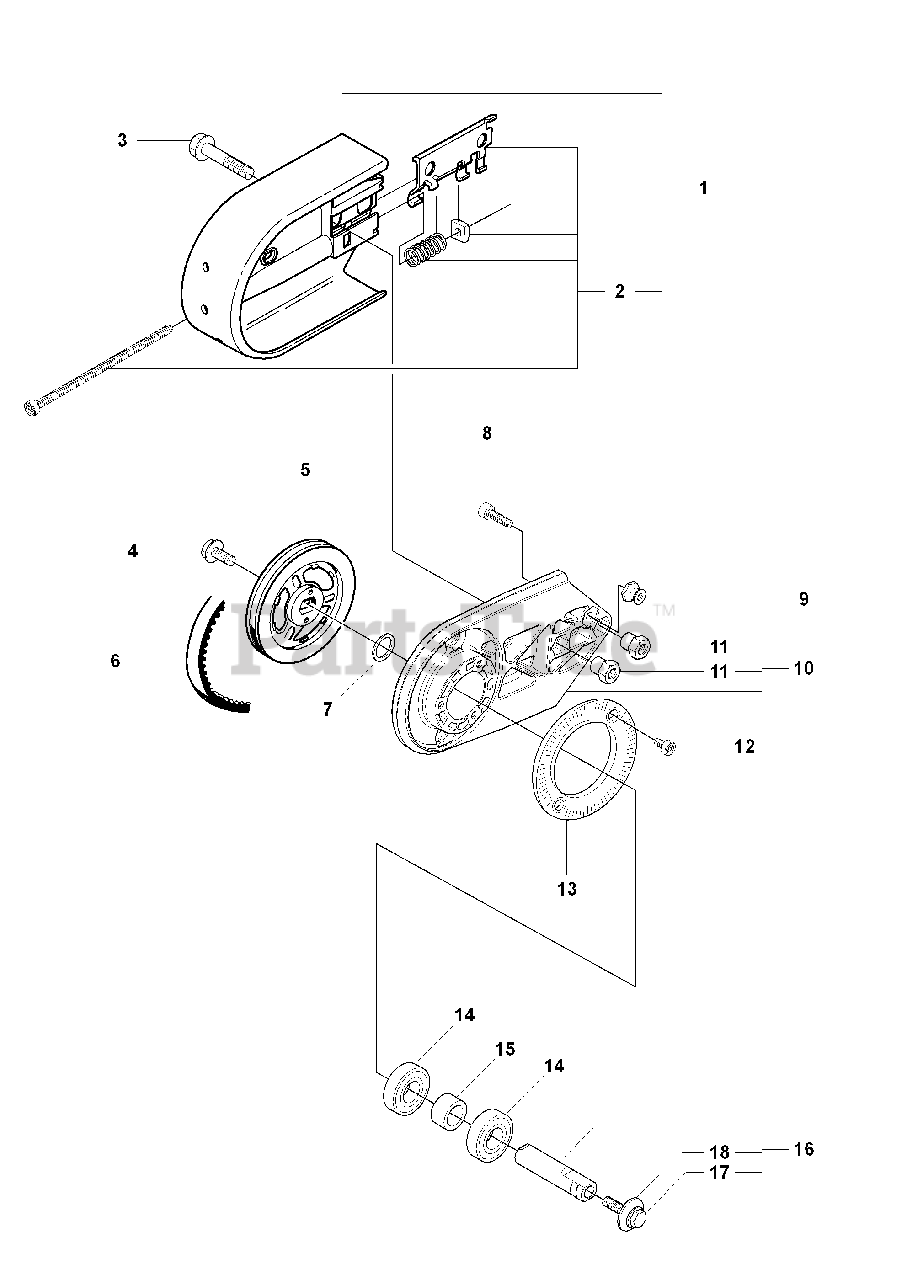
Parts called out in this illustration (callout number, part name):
1	BELT GUARD
2	BELT TENSIONER ASSY
3	COLLAR SCREW
4	SCREW COLLAR
5	PULLEY
6	BELT
7	WASHER STEEL
9	TORSION STOP
10	BEARING HOUSING
13	SCREEN PATTERN FLANG
14	BALL BEARING
15	SPACING SLEEVE
16	SHAFT
17	COLLAR SCREW
18	WASHER
